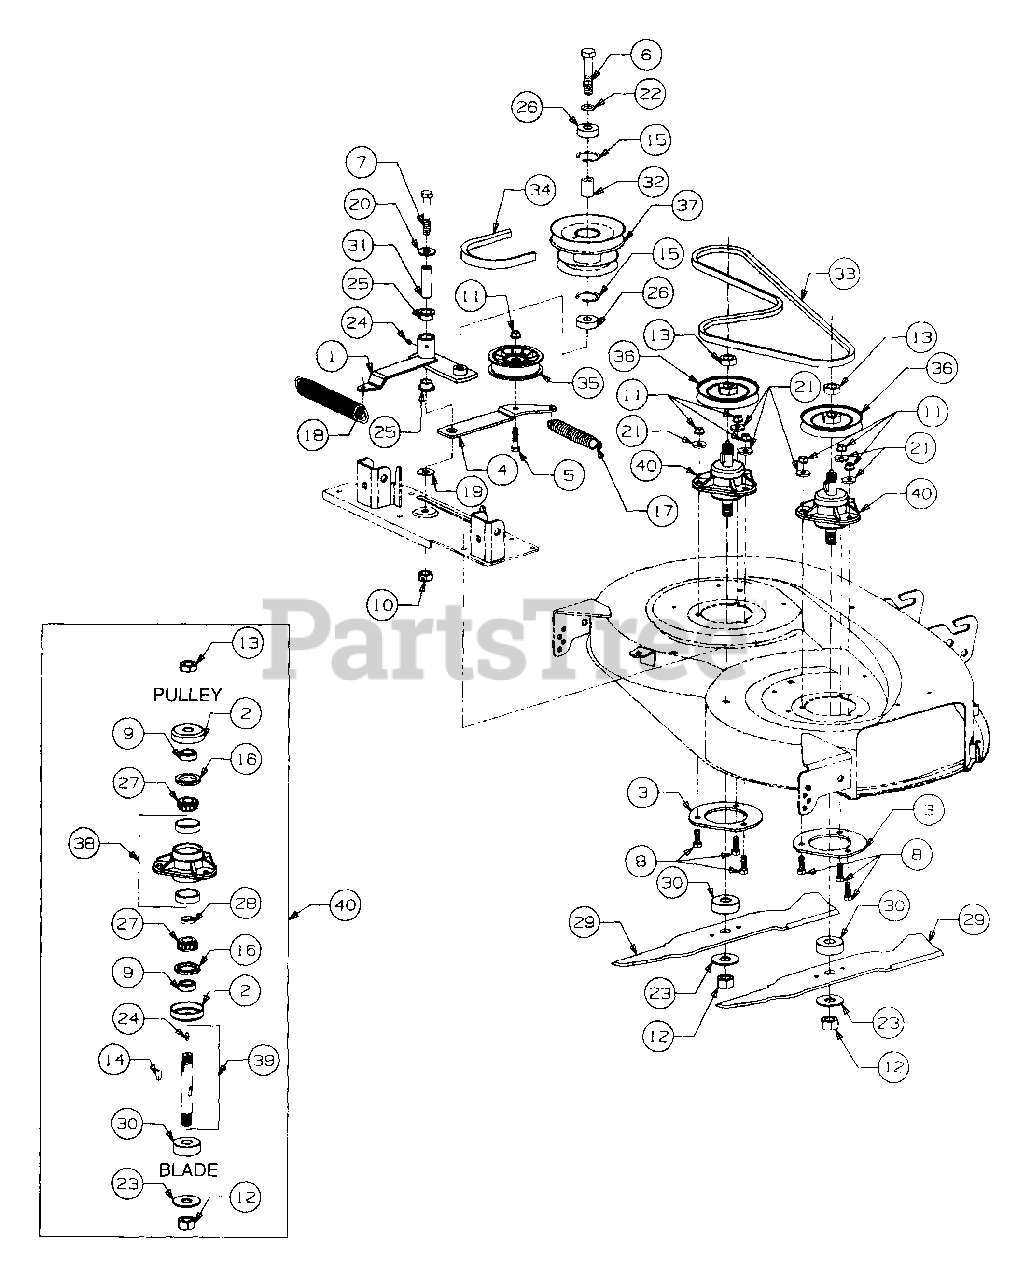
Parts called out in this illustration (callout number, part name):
2	Cup, Spindle Hdn
3	Plate, Spindle Mounting
5	Screw, Hex Cap, 3/8-16 x 1.5 GR5
6	Screw, Hex Cap, 5/8-18 x 3.0 GR5
7	Screw, Hex Cap, 1/2-20 x 3.0 GR8
8	Screw, Hex Cap, 3/8-16 x 1.25 GR5
9	Spacer, .755 x 1.25 x .44
10	Nut, Hex Center Lock, 1/2-20
11	Nut, Hex Flange Lock, 3/8-16
12	Nut, Hex, 3/4-16 GR8
13	Nut, Hex Jam, 3/4-16 GR5
14	Key, #91 Woodruff, 1/4 x 3/4 Hdn
15	Snap Ring, Internal
16	Seal, Oil, 1.25 x 1.874 x .25
17	Spring, Extension, .88 x 6.12
18	Spring, Extension, 1.25 x 8.15
19	Washer, Flat, .531 x 1.25 x .036
20	Washer, Flat, .531 x 1.25 x .100
21	Washer, Flat, .385 x 1.0 x .135
22	Washer Flat .63 x 1.0 x .063 Hdn
23	Washer, Flat, .781 x 2.0 x .105
24	Fitting, 3/16 Drive Lube
25	Bearing, Flange, 3/4 ID x .53 Lg
26	Bearing, Ball, .62 ID x 1.57 OD
27	Cone, Bearing
28	Spacer, Bearing
29	Blade, Low Lift, 19.38 Lg
30	Spacer
31	Spacer, Idlr Brkt, .50 ID x .75 OD x 2.25
32	Spacer, Pulley, .635 ID x .88 OD x 1.25
33	Belt, Spindle, A-Section x 59 Lg
34	Belt, PTO, B-Section x 112.4 Lg
35	Pulley, Flat Idler, 3.5 OD
36	V-Pulley, 4.62 OD
37	Pulley, Double
38	Housing w/Cups, Spindle
39	Kit, Shaft w/Seal
40	Spindle Assembly, Blade
